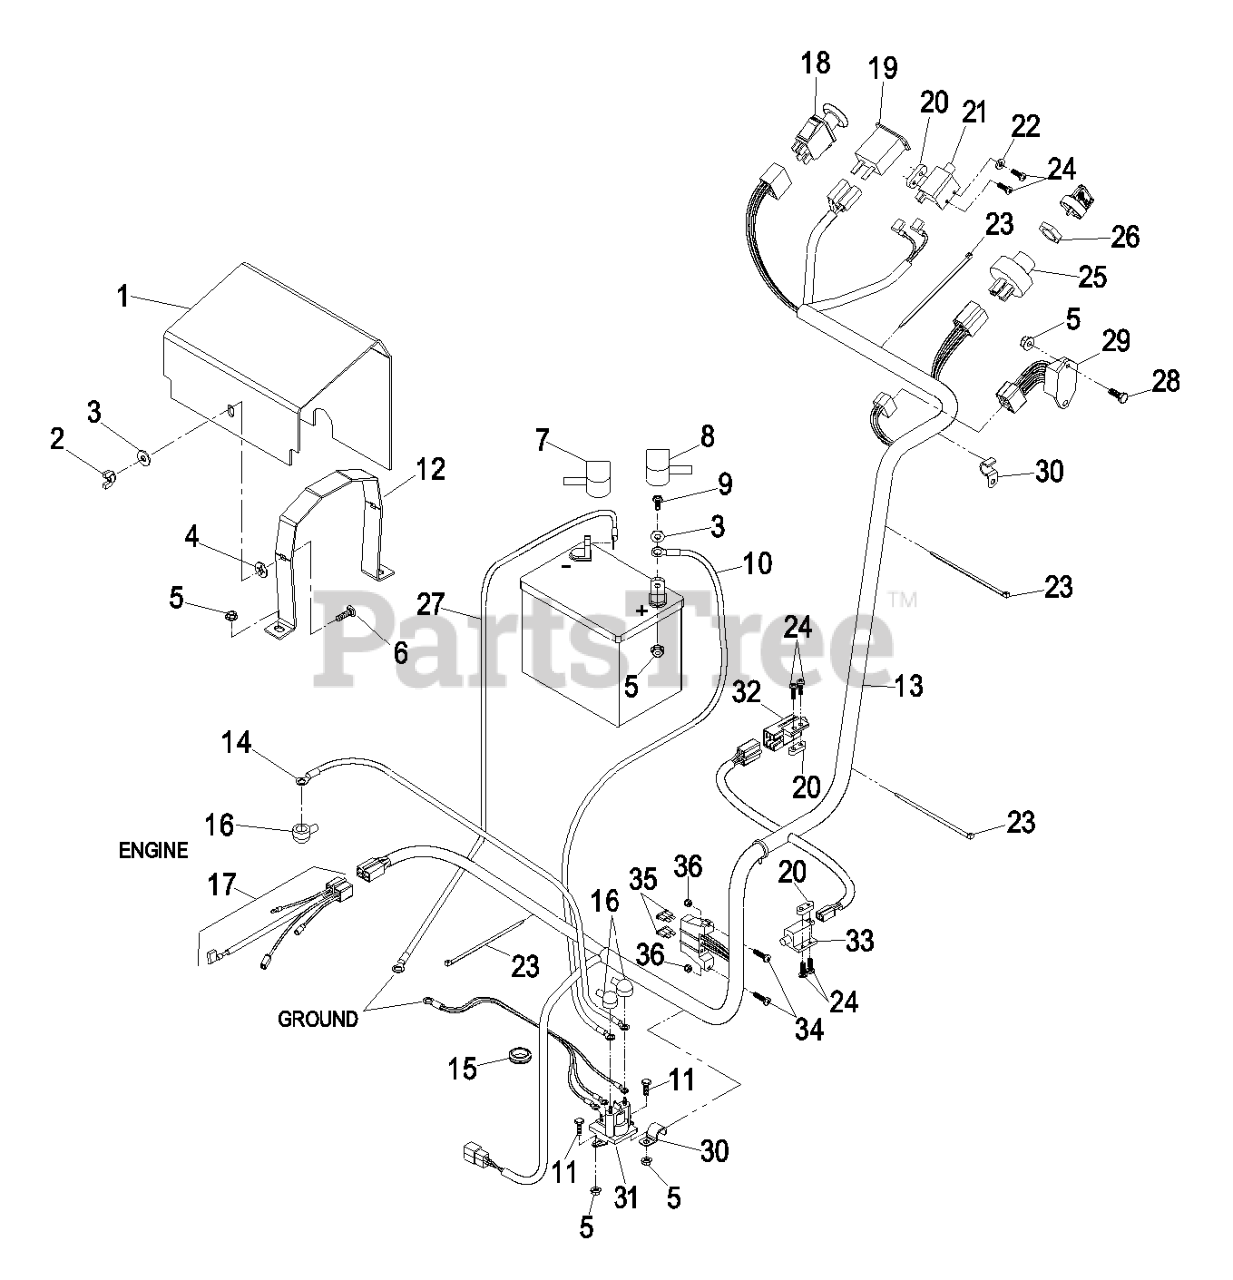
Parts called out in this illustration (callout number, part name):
1	COVER,BATTERY W/DECAL
2	NUT-WING
3	WASHER-FLAT
4	NUT-RETAINING
6	BOLT-CARR
7	INSULATOR, BATTERY -
9	SCREW-HH
11	SCREW-HH
12	STRAP,BATTERY HOLDDOWN
13	HARNESS,TTH ECS WIRING
15	GROMMET
16	INSULATOR-SOLENOID
17	HARNESS,WIRING 19KA
18	SWITCH-PTO
19	METER-HOUR
20	PLATE-TAPPED
21	SWITCH-OPEN, NORMALLY
22	WASHER-FLAT
23	TIE-PLASTIC
24	SCREW-PPH
25	SWITCH,IGNITION
26	NUT-SWITCH, IGNITION
27	WIRE-GROUND
28	SCREW-HH
29	MODULE-OPC NO TIME DELAY
30	CLIP-HALF, LOOM
33	SWITCH-CLOSED, NORMALLY
34	SCREW-HEAD, TRUSS
35	FUSE-BLADE TYPE, 20 AMP
36	NUT-LOCK, NI
